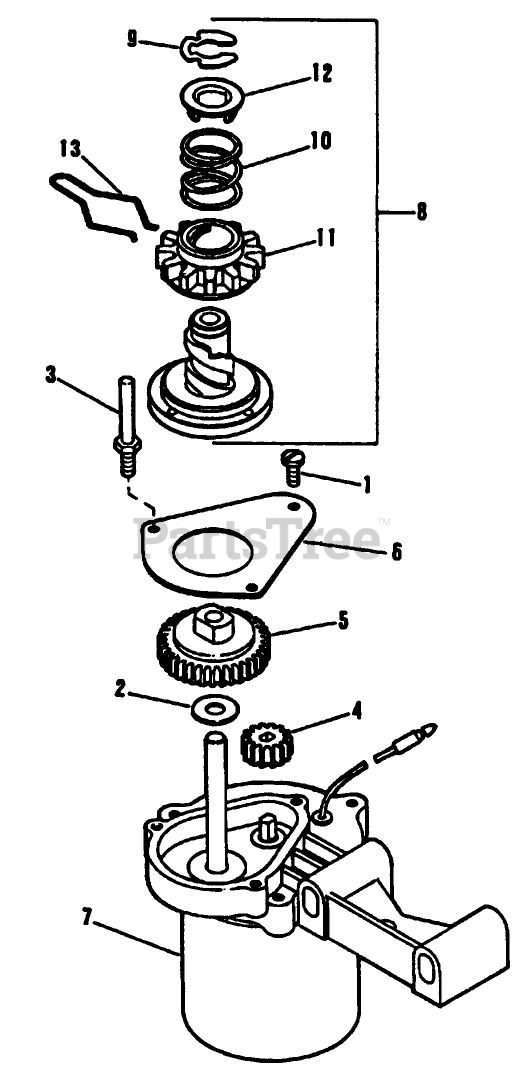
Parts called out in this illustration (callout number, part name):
1	SCREW EF
4	PINION SM
6	GEAR COVER EF
9	RET.RING EF
10	*SPRING PINION EF
11	PINION SM
12	STOP WASHER EF
13	SPRING - DRAG
